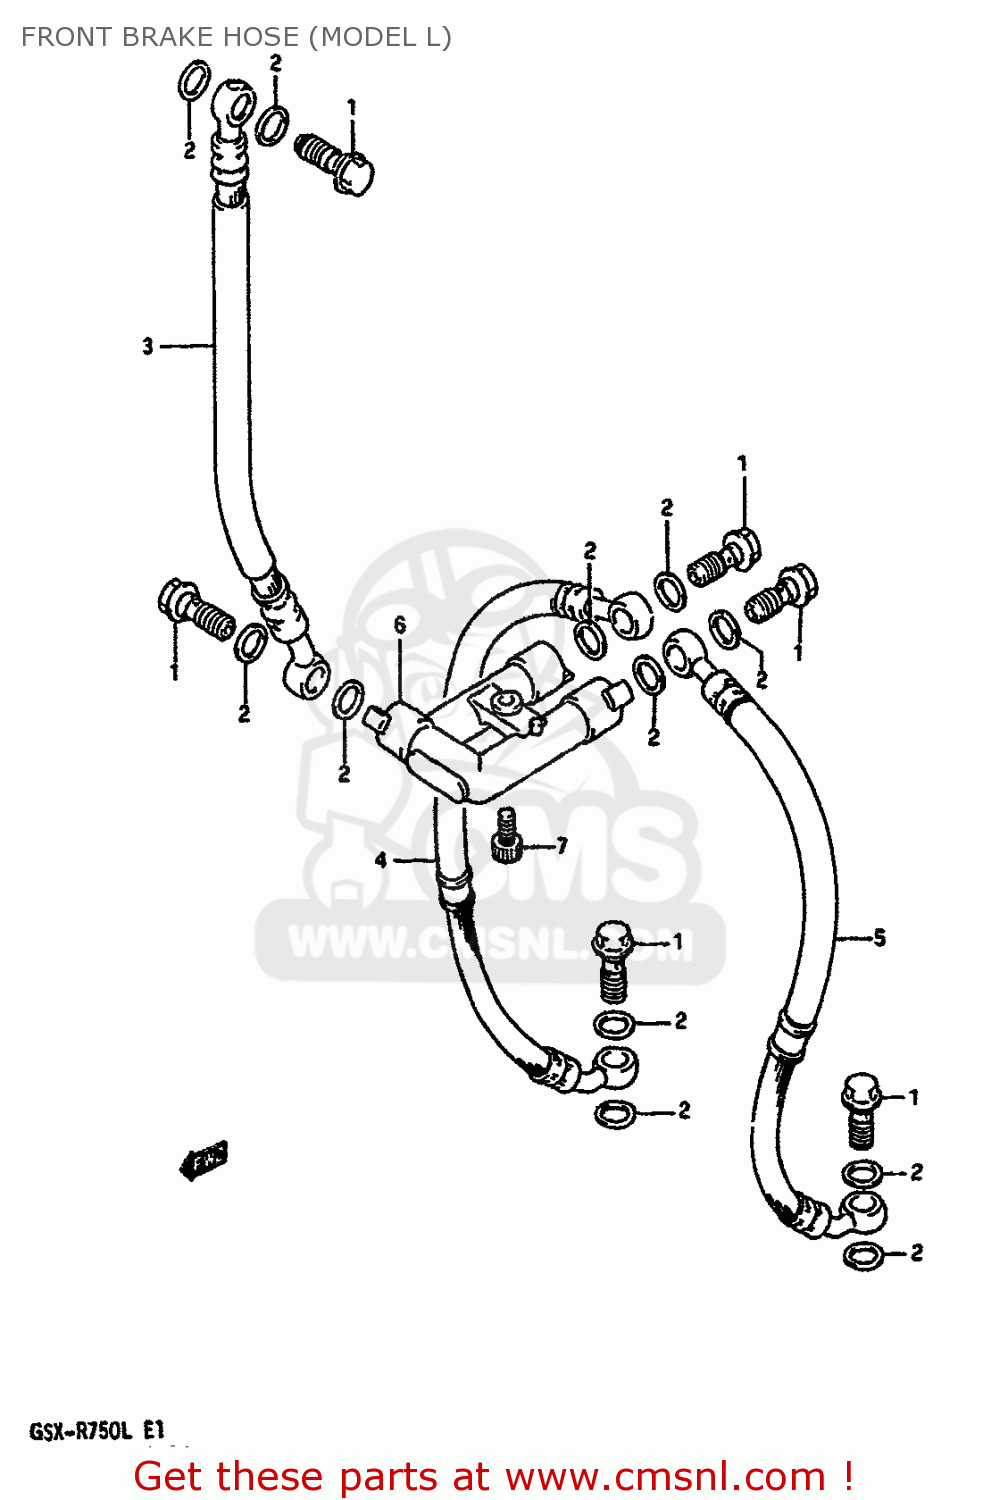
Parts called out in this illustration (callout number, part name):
1	BOLT UNION
2	WASHER(10X15X1.5)
3	HOSE COMP,FRONT BRAKE
4	HOSE COMP,FRONT BRAKE
5	HOSE,FR BRAKE NO.2,L
6	JOINT,BRAKE HOSE
7	BOLT
8	ADAPTER,BRAKE HOSE
